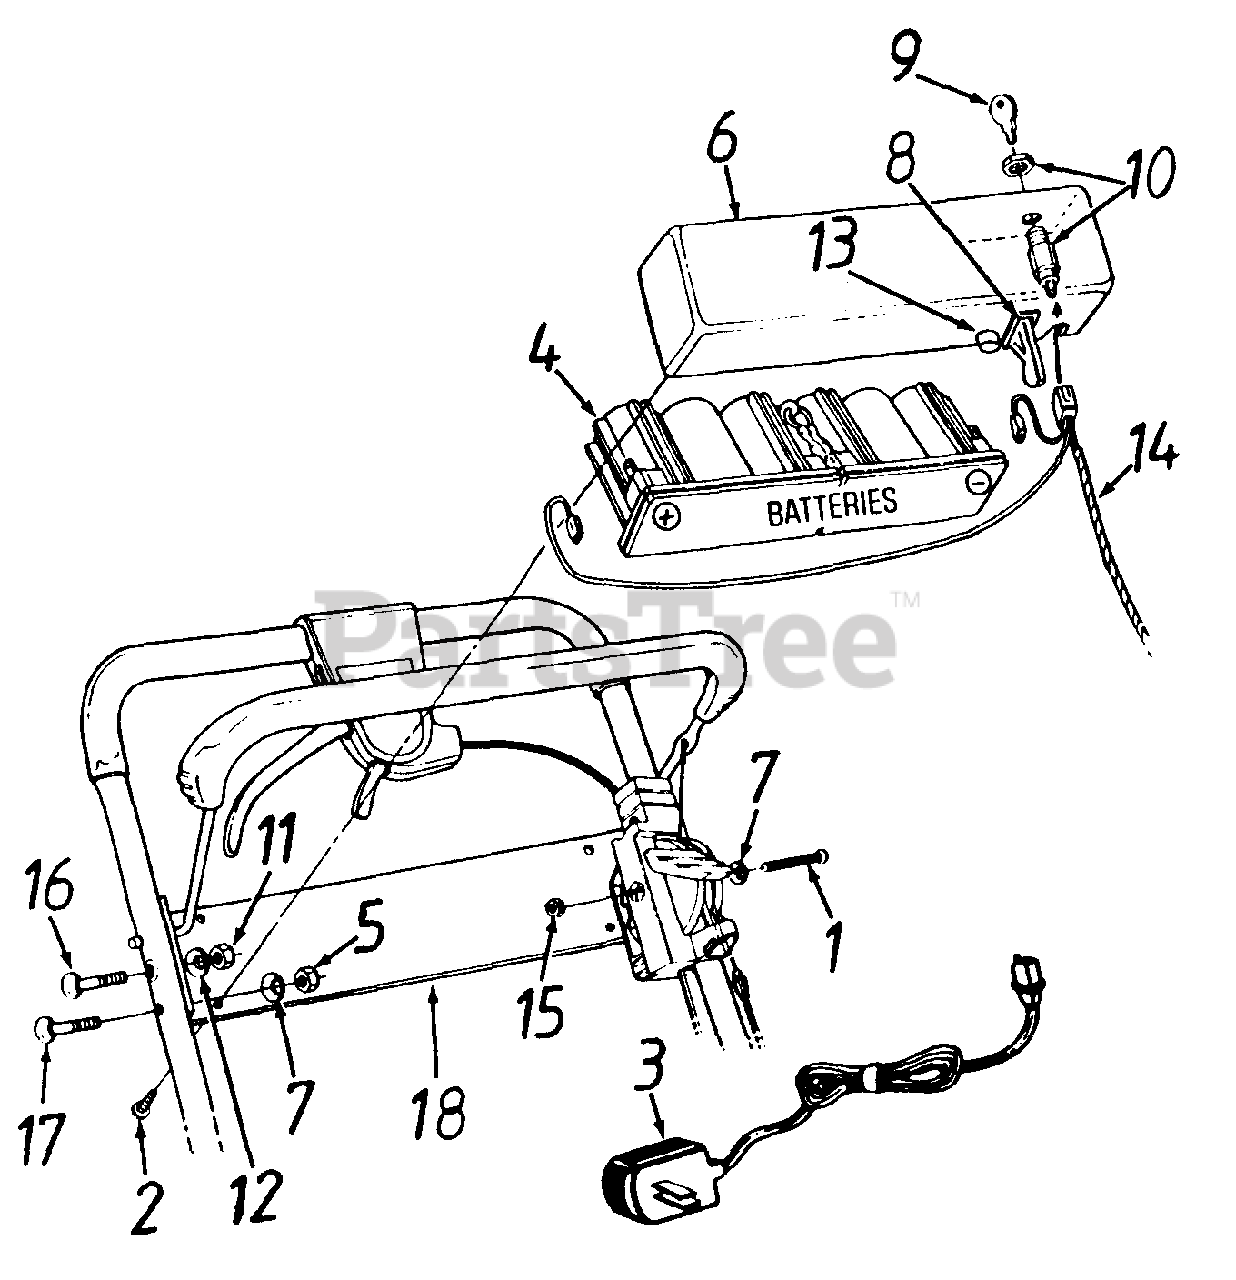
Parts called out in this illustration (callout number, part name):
1	Hex Bolt 1/4-20 x 2" Lg.
2	Truss Mach. Hi-Riser Tap Scr. 1" Lg.
3	Battery Charger
4	Battery Pack - 12 Volt
6	Battery Tray
8	Plug
9	Ignition Key
10	Ignition Switch
11	Hex Nut 5/16-18 Thd.
12	Bell-Wash. 5/16" I.D.
13	Fuse Holder
14	Wire Harness
15	Hex I-Nut 1/4-20 Thd.
16	Carr. Bolt 5/16-18 x 1.38" Lg.
17	Carr. Bolt 1/4-20 x 1.25" Lg.
